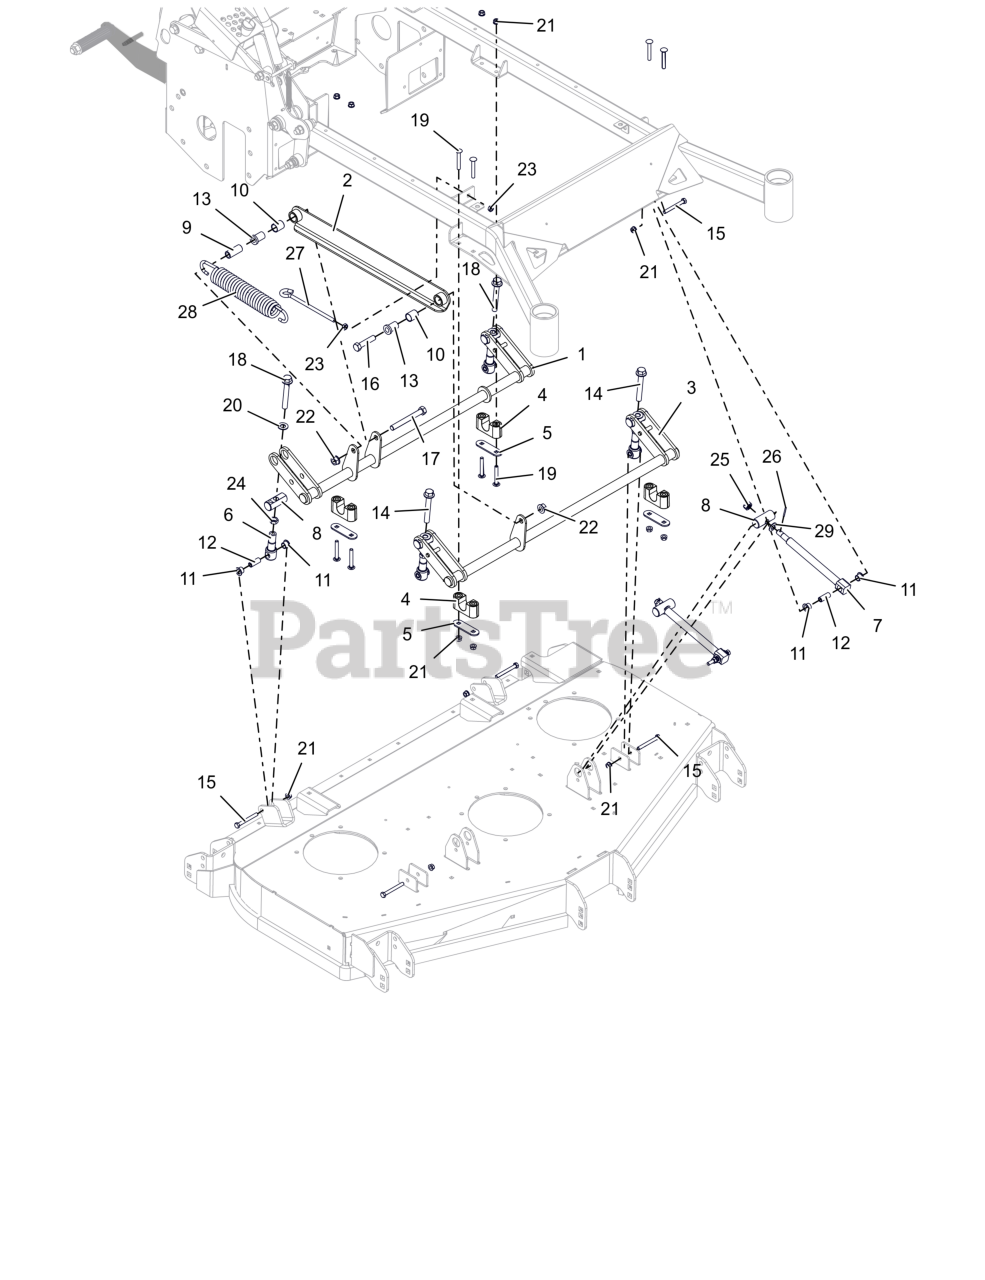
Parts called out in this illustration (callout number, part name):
1	WLDMT, DECK LIFT
2	LINK, DECK LIFT
3	WLDMT, FRONT DECK LIFT (BLACK)
4	ASM-BUSHING, DECK LIFT
5	PLATE, BEARING SUPPORT
6	LINK, DECK LIFT FORMED
7	DRAG,LINK-HD
8	PIN, DECK LIFT
9	BSHG, FLANGE .515 X .750 X 1.544 X 1.000
10	BRG, .750 X .875 X 1.000
11	BSHG, FLANGED .50X.625X.50X.062
12	SPCR, .31X.50X1.265
13	BSHG-FLG .515X.746X1.290X1.000
14	BLT, .500-13 X 3.500 GR5 ZC
15	BLT, HEX .31-18X2.75 G5 ZCC
16	BLT, HEX .50-13X2.25 G5 ZCC
17	BLT, HEX 0.5-13X4.25 GR5 ZCC
18	BLT, .500-13 X 3.500 GR5 ZC
19	BLT, RHSSN.31-18X2.25 G5 ZCC
20	WSHR, FLT .557X1.040X.102 ZCC
21	NUT,LK-CTR-FLG .31-18 GF ZCC
22	NUT-LK-CTR-FLG .500-13 GG ZCC
23	NUT-JAM .375-16 G2 ZCC
24	NUT-JAM .500-13 G2 ZCC
25	NUT-SL .50-13
26	PIN,CTR.12X1.25EXTPRSQCT ZC120
27	BOLT, .38-16X6.00 .62 DIA EYE
28	SPRG, EXTENSION - .273X1.853X.10.125
29	WSHR, BLVL .505 X 1.000 X .073 ZCC
